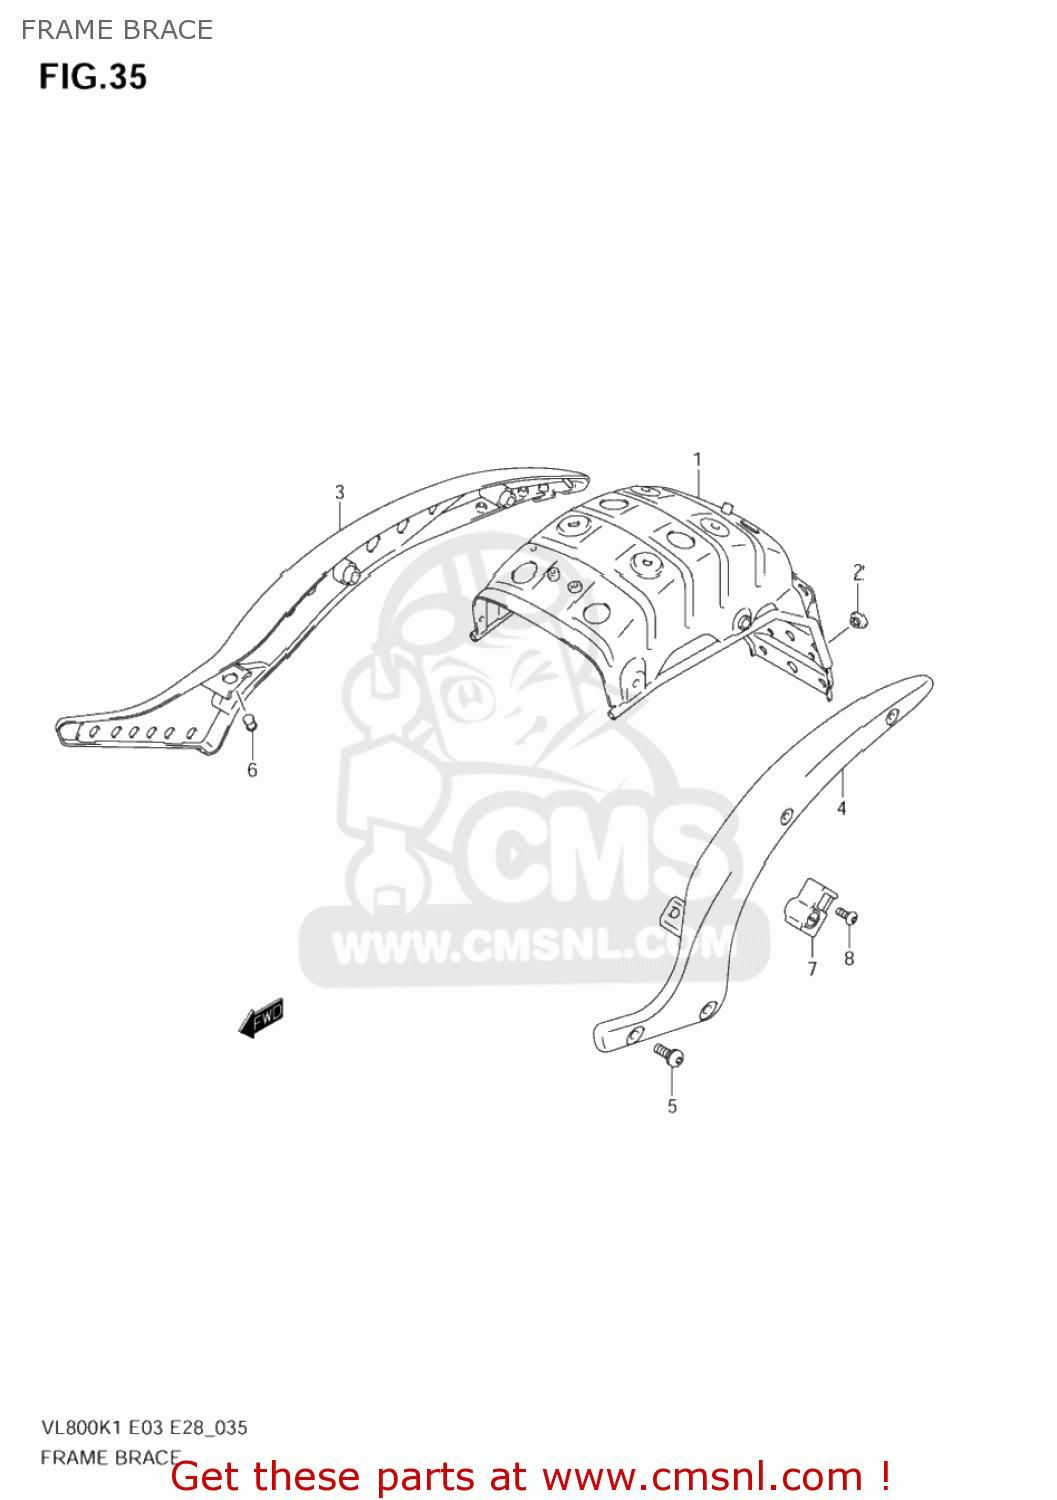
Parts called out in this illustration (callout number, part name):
1	BRACE COMP,REA
2	CUSHION
3	GRIP,FRAME HANDLE,R
4	GRIP,FRAME HANDLE,L
5	BOLT(10X25)
6	PLUG(OD:9)
7	LOCK SET,HELME
8	SCREW(6X14)
